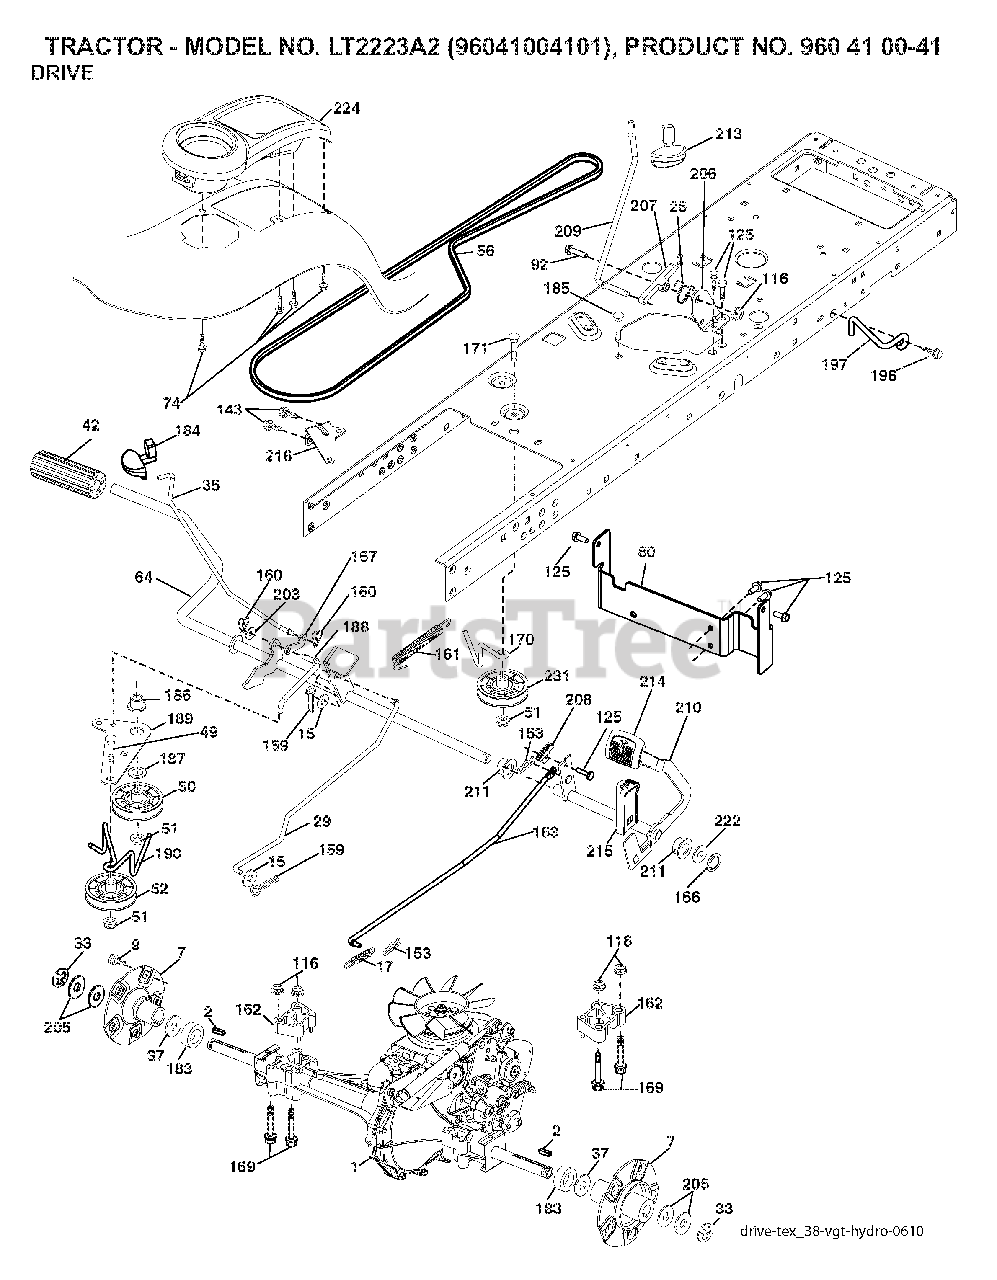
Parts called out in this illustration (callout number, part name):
2	KEY.SQUARE.187X2.500
7	HUB.ASM.WHEEL.REAR.22"
17	SPRING.BRAKE.HG3000/3500
26	SPRING.RETURN.CRUISE
29	ROD.BRAKE.0610.PEDAL.CONTROL
33	E-RING LT
35	ROD.BRKAE.PARKING.STEALTH
42	PEDAL COVER T
49	BOLT
50	IDLER.FLAT.910.OFFSET
51	NUT LOCK FLG 3/8-16 UNC
52	IDLER.V-GROOVE.910.OFFSET
64	SHAFT.ASM.PEDAL.BRK.CNTR
74	SCREW.HI-LO.CONSOLE
80	BRKT.STRP.TRQ.LT.HYD.C
92	BOLT
116	NUT LOCK HEX FLANGE 5/16-18
125	SCREW
153	RETAINER M
159	COTTER PIN
160	RETAINER CLIP
161	SPRING.RETURN.CLUTCH.2006
162	SPACER.TRANSAXLE.18&22
163	ROD.PEDAL.CONTROL.0510
166	NUT.PUSH.625.2006
167	LATCH.BRAKE.SPRING
169	BOLT.HEX.FLNG.5/16-18X3.75
170	KEEPER.V-IDLER.CENTER.
183	SPACER.SPLIT.800X.350
184	HANDLE.PRKG.BRAKE.STLTH.TX.RED
186	SPACER.RETAINER
187	WASHER 12/32X2X10GA
188	LINK.CLUTCH.GROUND.DRIVE
189	BELLCRANK.GROUND.DRIVE.TEX.
190	KEEPER.BELLCRANK.DRIVE
196	SCREW 3/8-16X1
197	BRKT.ANIT-ROTATION.CLU
203	WASHER
206	BRKT.MOUNT.LATCH.CRUIS
207	LATCH.CONTROL.CRUISE
208	GEAR.SECTOR.CONTROL.CR
209	ROD.CONTROL.CRUISE.STEALTH.TEX
210	ROCKER.ASM.PEDAL.CONTR
211	BEARING.NYLON
213	KNOB.CONTROL.CRUISE
214	PEDAL.FORWARD.TEX.GT.4
215	PEDAL.REVERSE.TEX.GT.4
216	BRACKET.PULLEY.IDLER.W/TEX
222	WASHER 21/32 X 1-1/4 X 10 GA.
224	CONSOLE.TOOLBOX.PCH.ERGO.BLACK
231	IDLER.V-GROOVE.1.688.OFFSET
